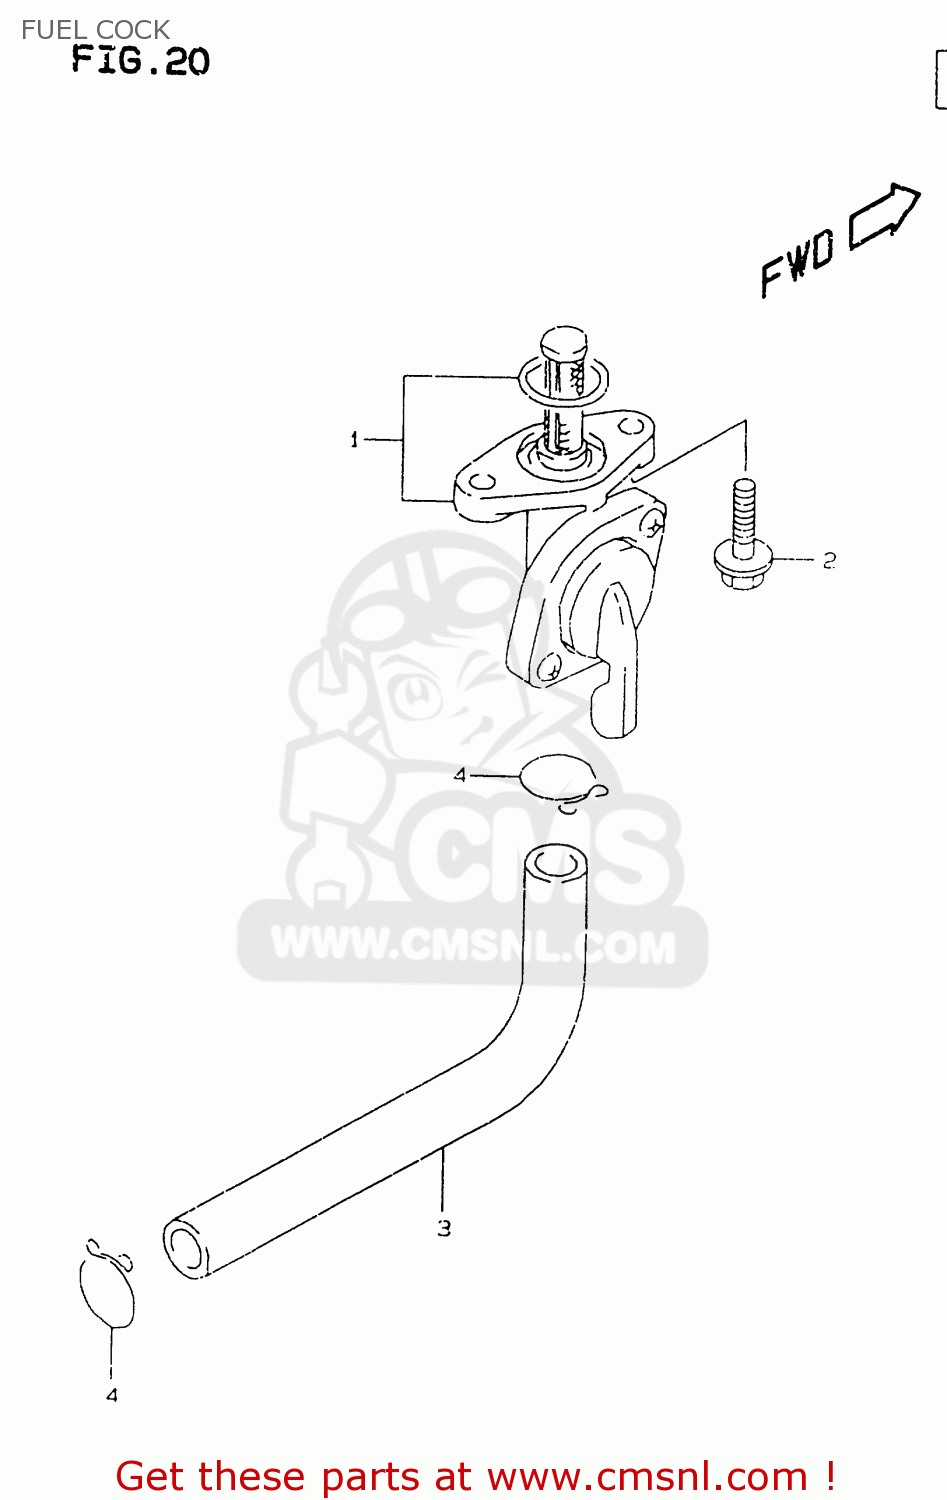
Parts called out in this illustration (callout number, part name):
1	COCK ASSY,FUEL
2	BOLT
3	HOSE(7X12X600)
4	CLIP
